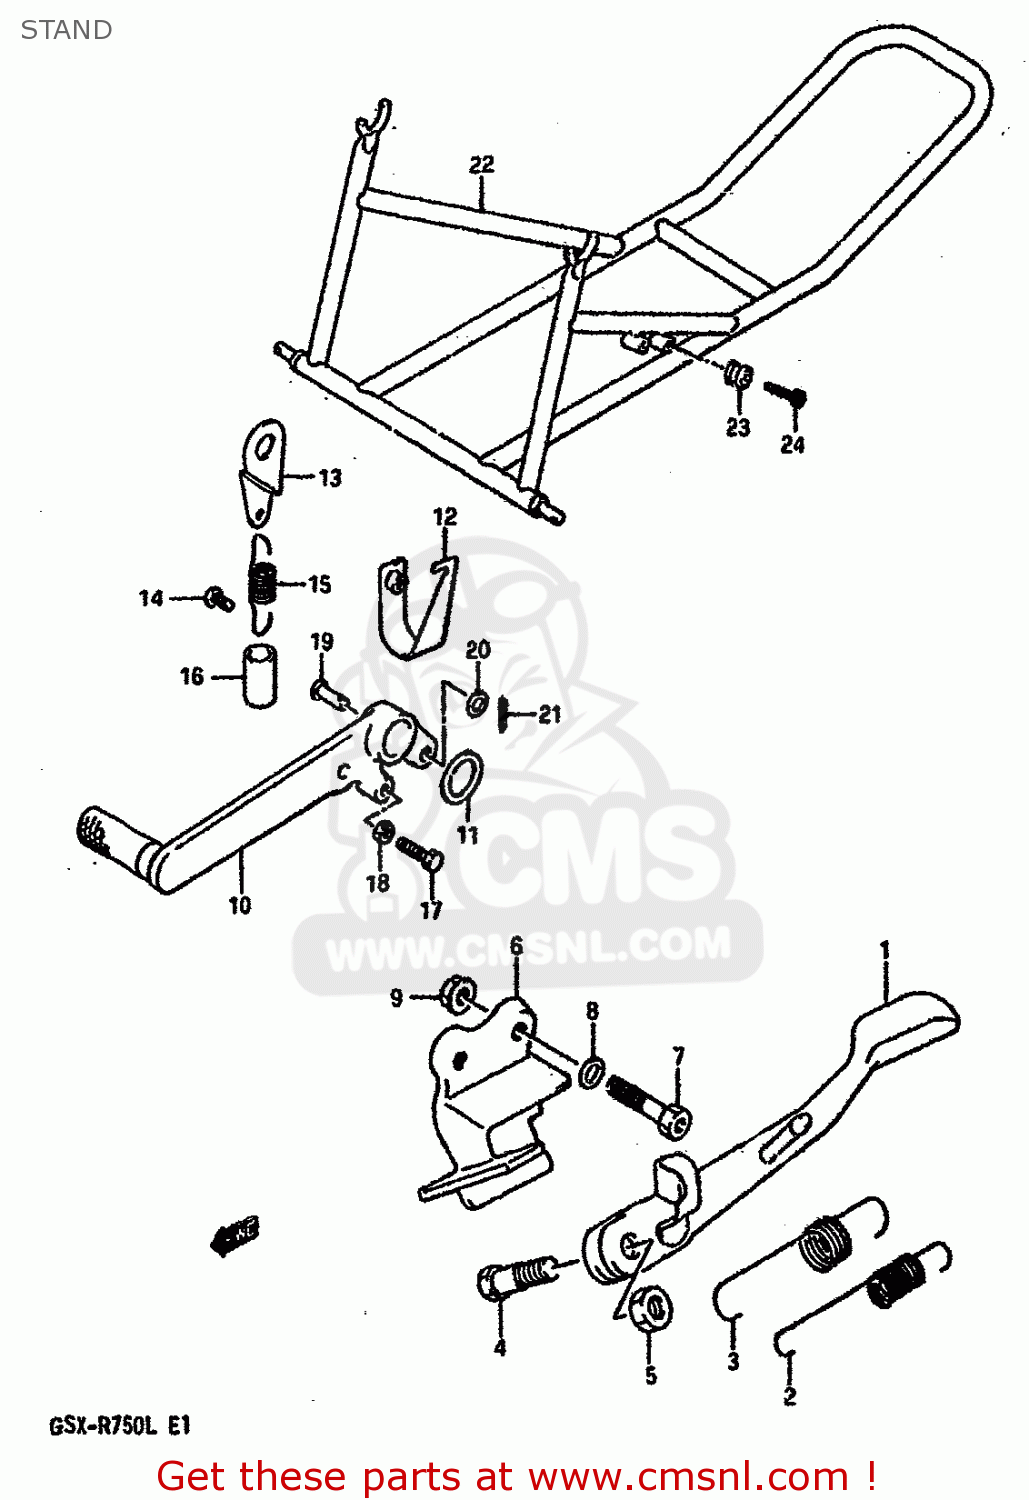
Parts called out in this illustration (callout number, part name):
1	STAND,SIDE
2	SPRING
3	SPRING
4	BOLT(10X38)
5	NUT
6	BRACKET,SIDE STAND
7	BOLT, FRONT RH
8	WASHER
9	NUT
10	PEDAL,BRAKE
11	WASHER(18X24X1)
12	PLATE,BRAKE SPRING,FRONT
13	BRACKET,STOP SWITCH SPRING
14	SCREW(6X12)
15	SPRING
16	TUBE,BRAKE SPRING GUIDE
17	BOLT
18	NUT
19	PIN
20	WASHER
21	PIN
22	STAND ASSEMBLY,REAR
23	HOLDER,STAND
24	BOLT, REAR (8X30)
